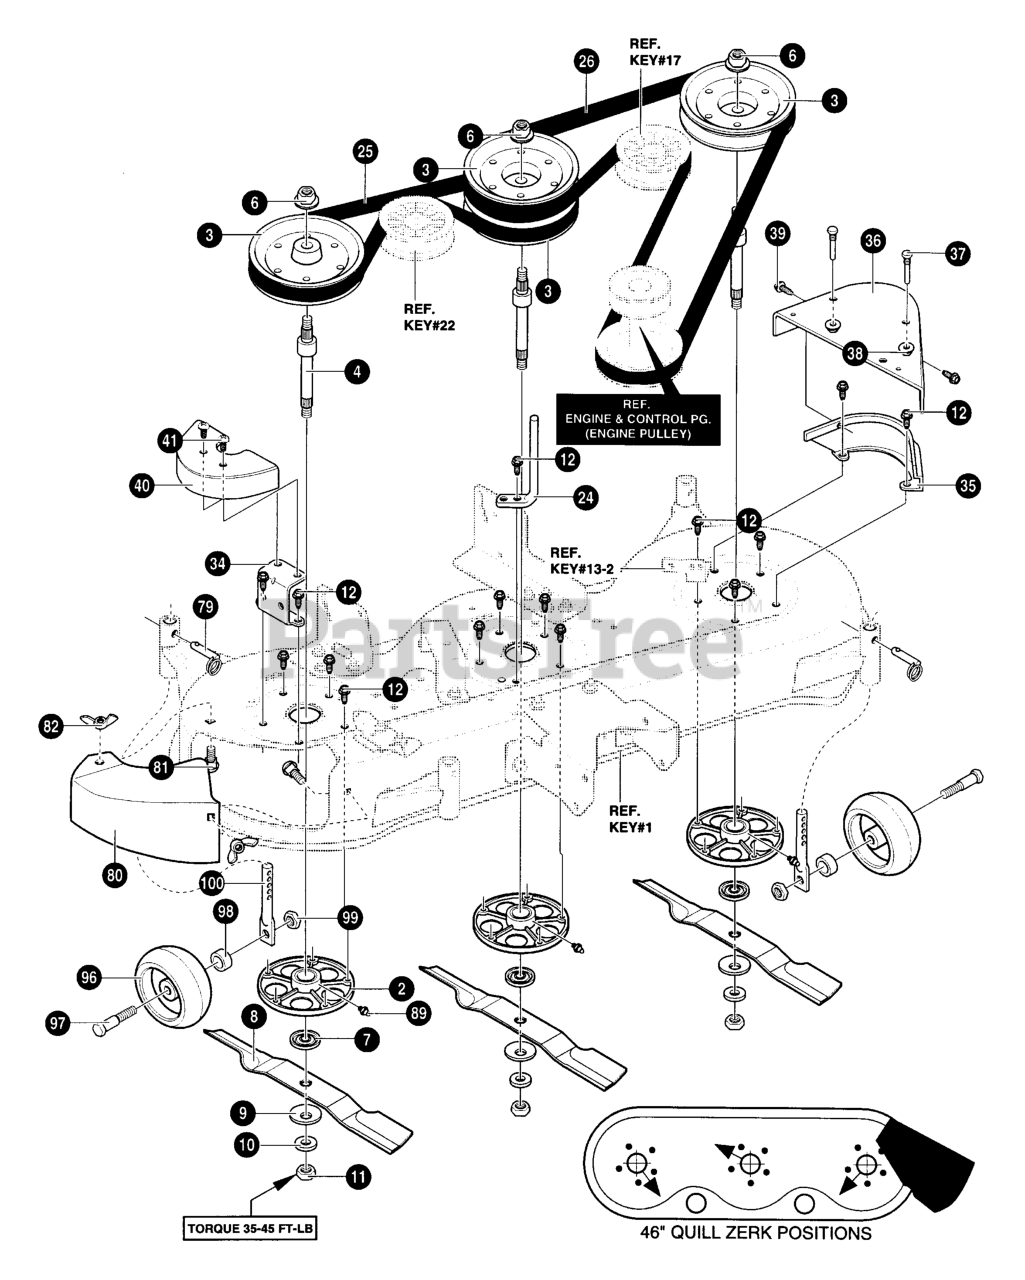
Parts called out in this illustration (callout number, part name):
2	JACKSHAFT
3	PULLEY
4	SHAFT, JACKSHAFT
7	HUB, BLADE ADAPTER
8	BLADE, MULCHER
12	SCREW
24	ROD, BELT GUIDE
34	BRACKET, PULLEY COVER
35	BRACKET, PULLEY COVER
36	PULLEY, COVER
37	SCREW, GUIDE 5/16-18
38	NUT, 5/16- 18
40	COVER, RIGHT PULLEY
41	SCREW
79	PIN, RING
80	PLATE, MULCHER
81	SCREW, 5/16-18 x 0.75
82	WINGNUT
89	ZERK, GREASE FITTING
96	WHEEL, GAUGE
97	BOLT, 3/8- 16
98	SPACER
99	NUT, 3/8- 16
100	ROD, GAUGE
